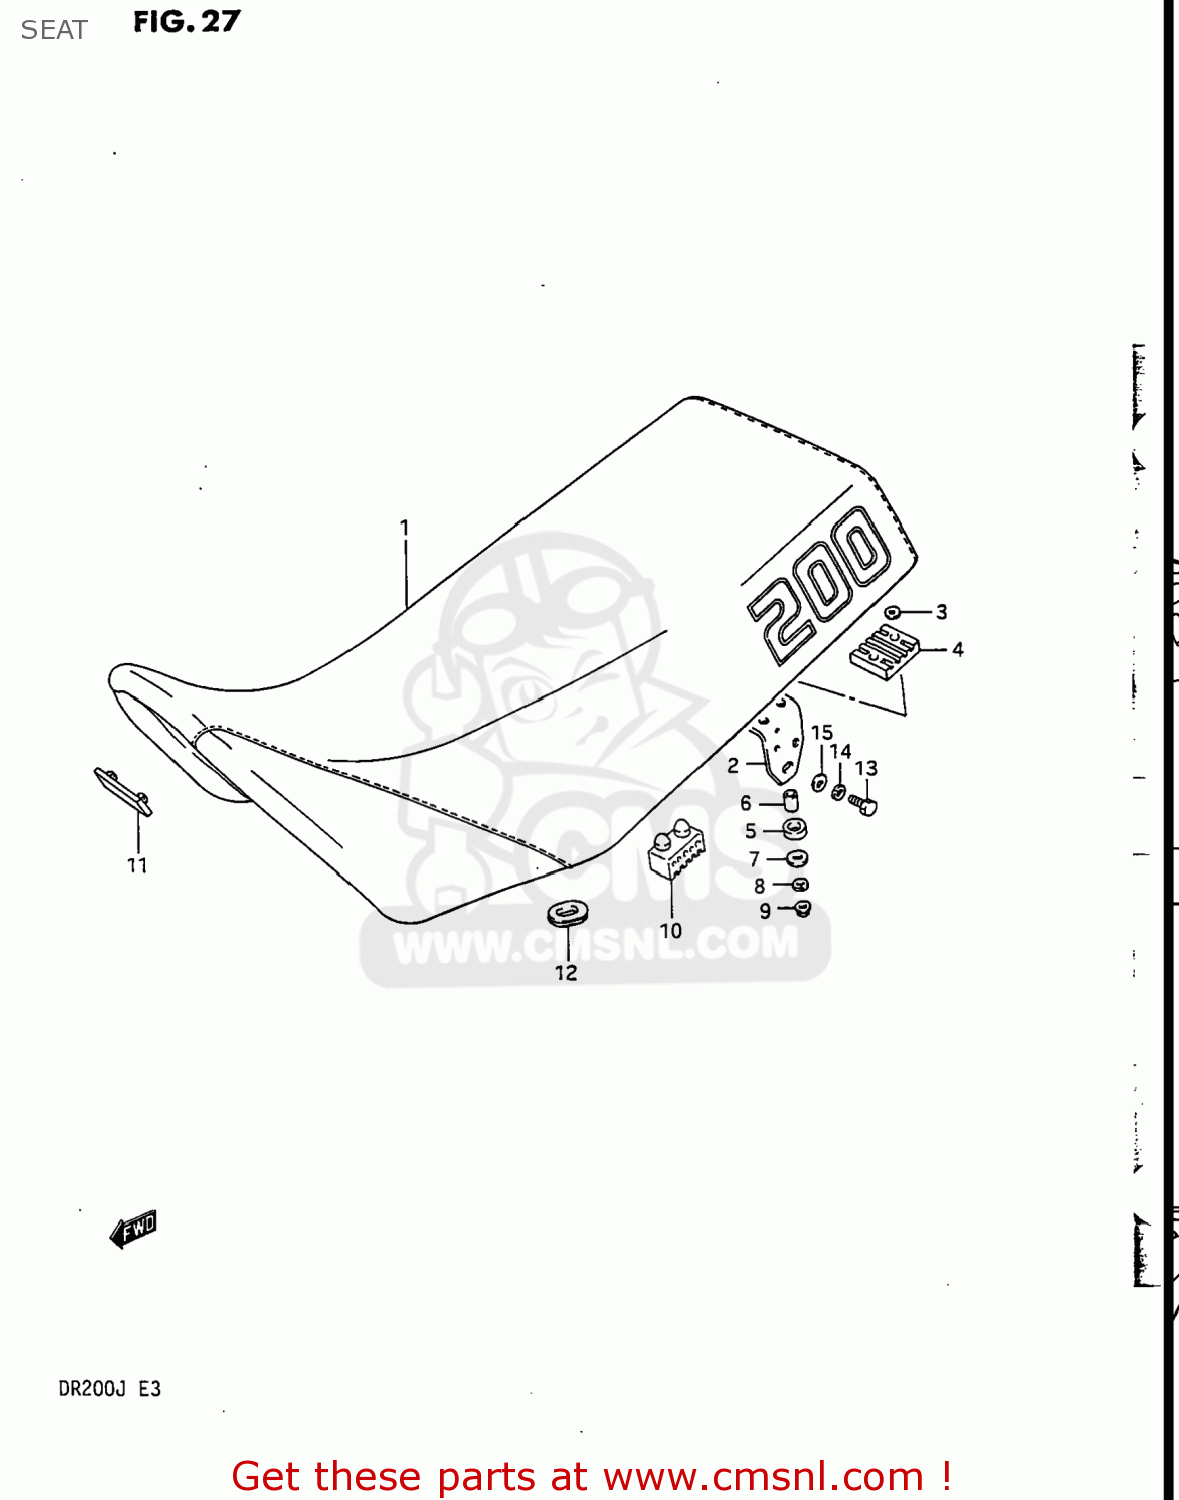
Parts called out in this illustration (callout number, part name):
1	SEAT ASSEMBLY
2	BRACKET,LEFT
3	WASHER, LOWER
4	CUSHION,FR PLATE
5	CUSHION,SEAT FR
6	SPACER,SEAT SUPPORT
7	WASHER
8	WASHER,LOCK
9	NUT
10	CUSHION,SEAT(40X20X15)
11	CUSHION
12	CUSHION
13	BOLT
14	WASHER,LOCK,8.
15	WASHER
